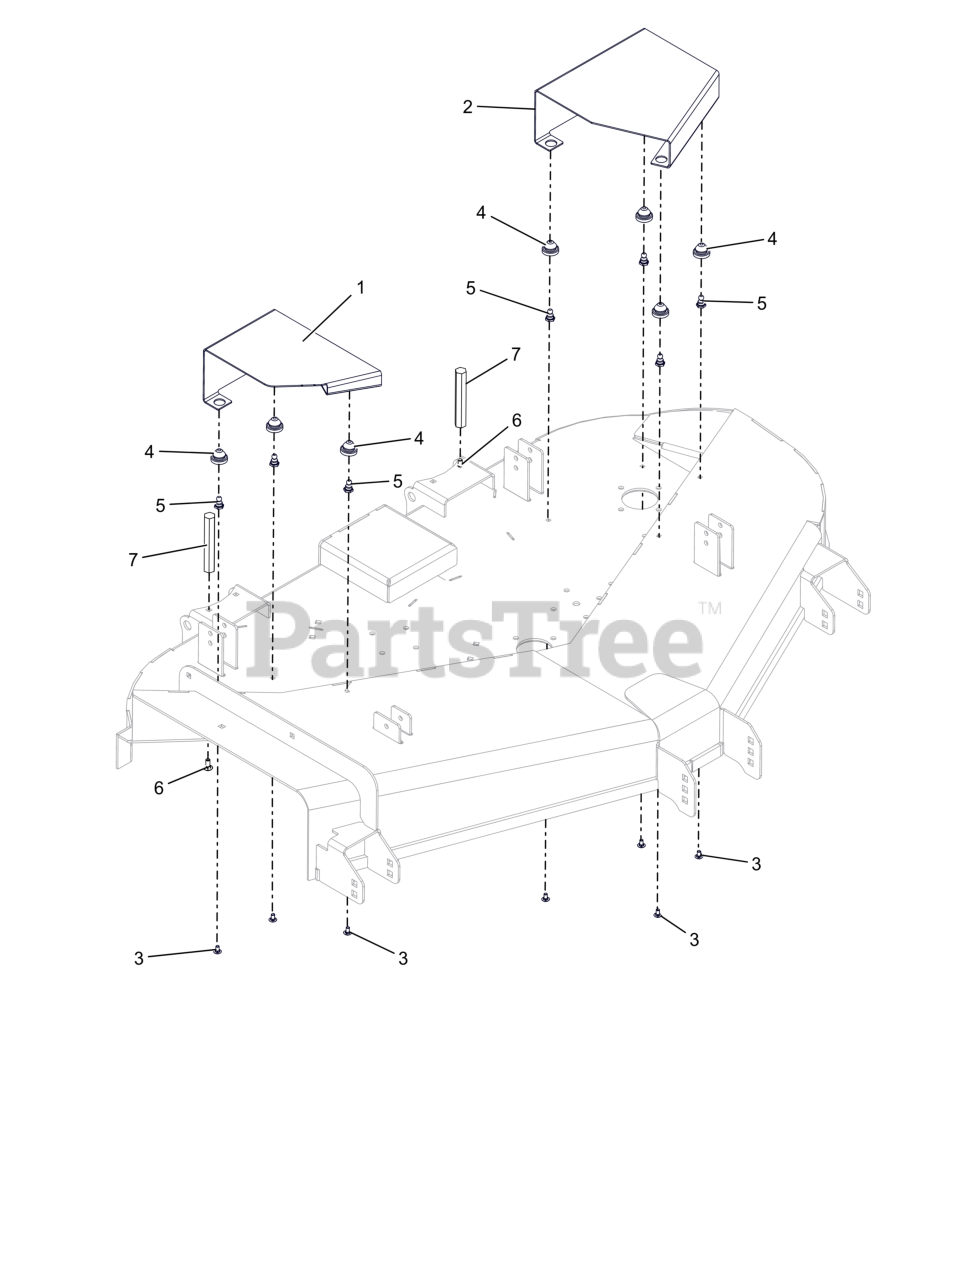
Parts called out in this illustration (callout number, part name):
1	COVER, RH BELT - TUNNEL DECK (RED)
2	COVER, LH BELT - TUNNEL DECK (RED)
3	BLT, RHSSN.25-20X.500 G5 ZCC
4	COUPLING, RUBBER PUSH-IN
5	STUD, BALL FEMALE .250-20 THREAD
6	BTL,RHSN .313-18 X 0.75 G5 ZCC LT
7	NUT, COUPLING .312-18 X 5.000
